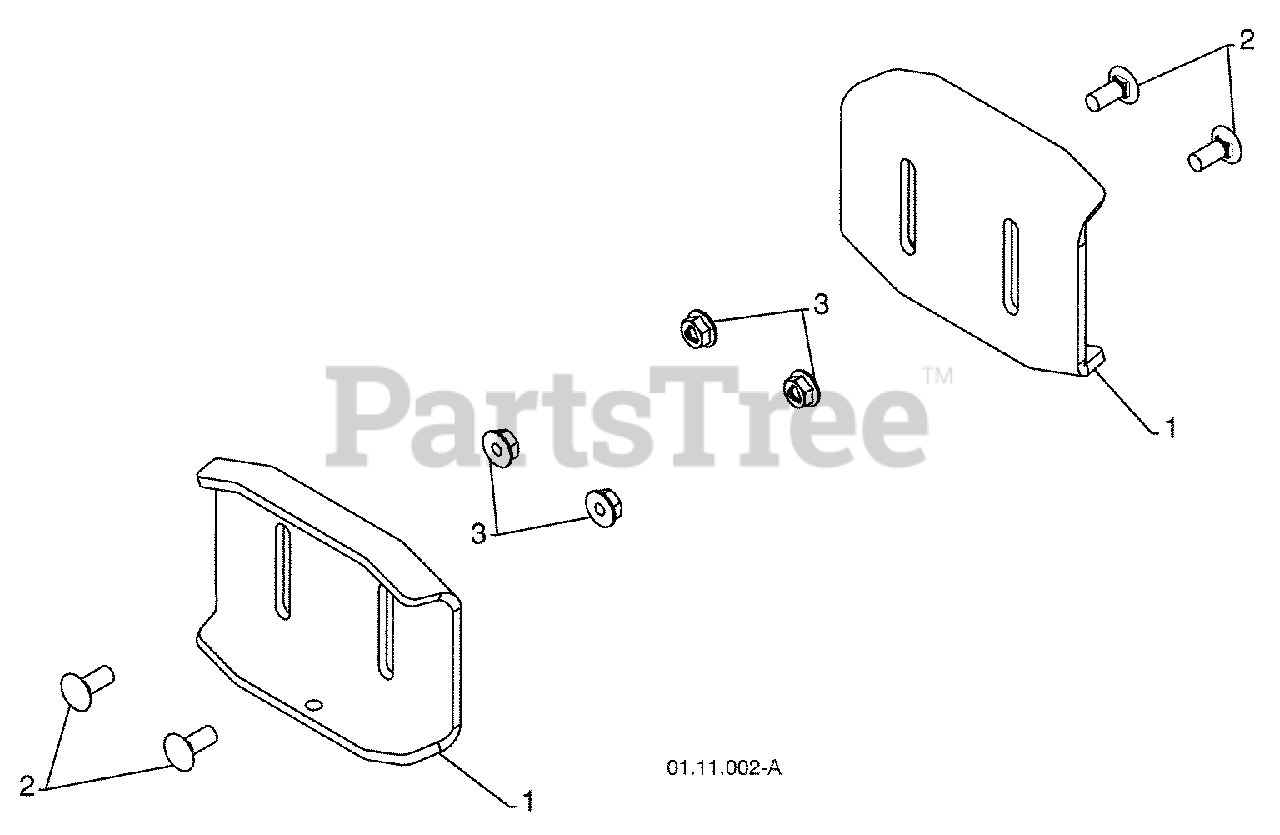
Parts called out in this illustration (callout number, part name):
1	SKID PLATE
2	CARRIAGE BOLT 5/16-18 X .750
3	NUT 5/16-18
